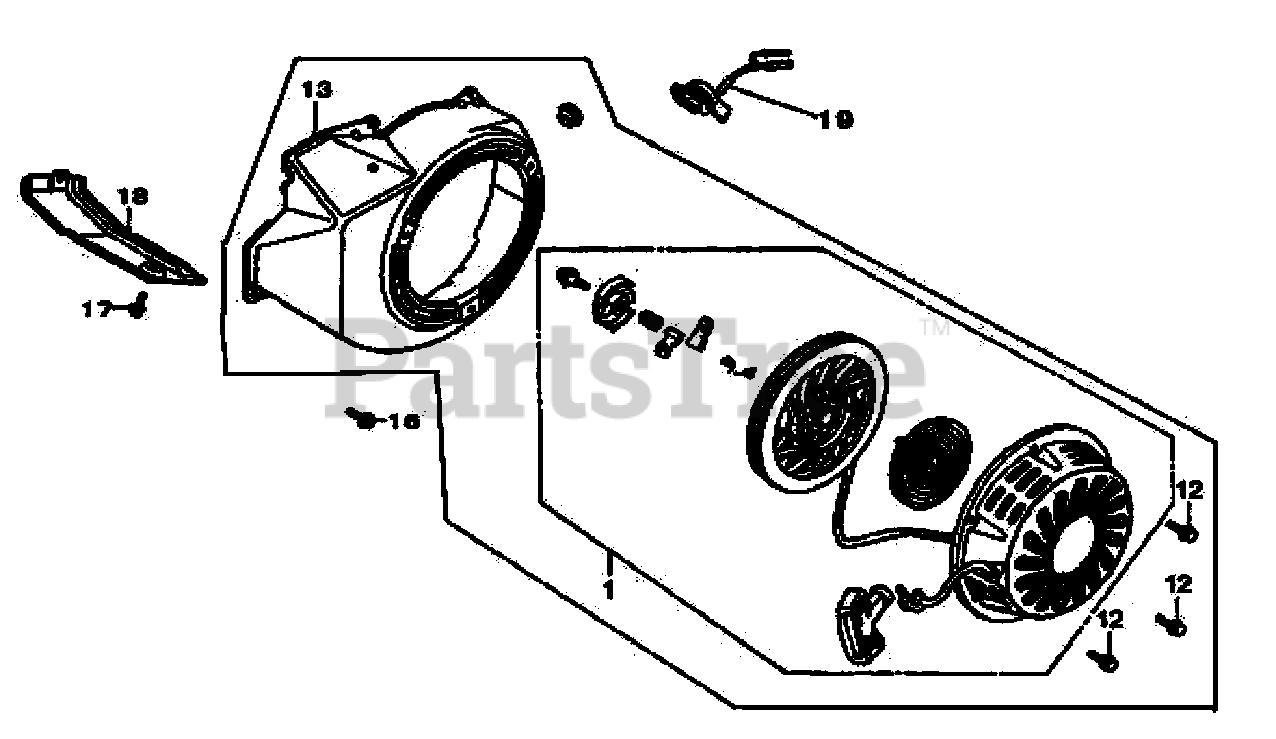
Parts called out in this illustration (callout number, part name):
1	STARTER ASSY., RECOIL
12	BOLT, FLANGE
13	COVER COMP., FAN
16	BOLT, FLANGE
17	BOLT, FLANGE
19	SWITCH ASSY., ENGINE STOP
